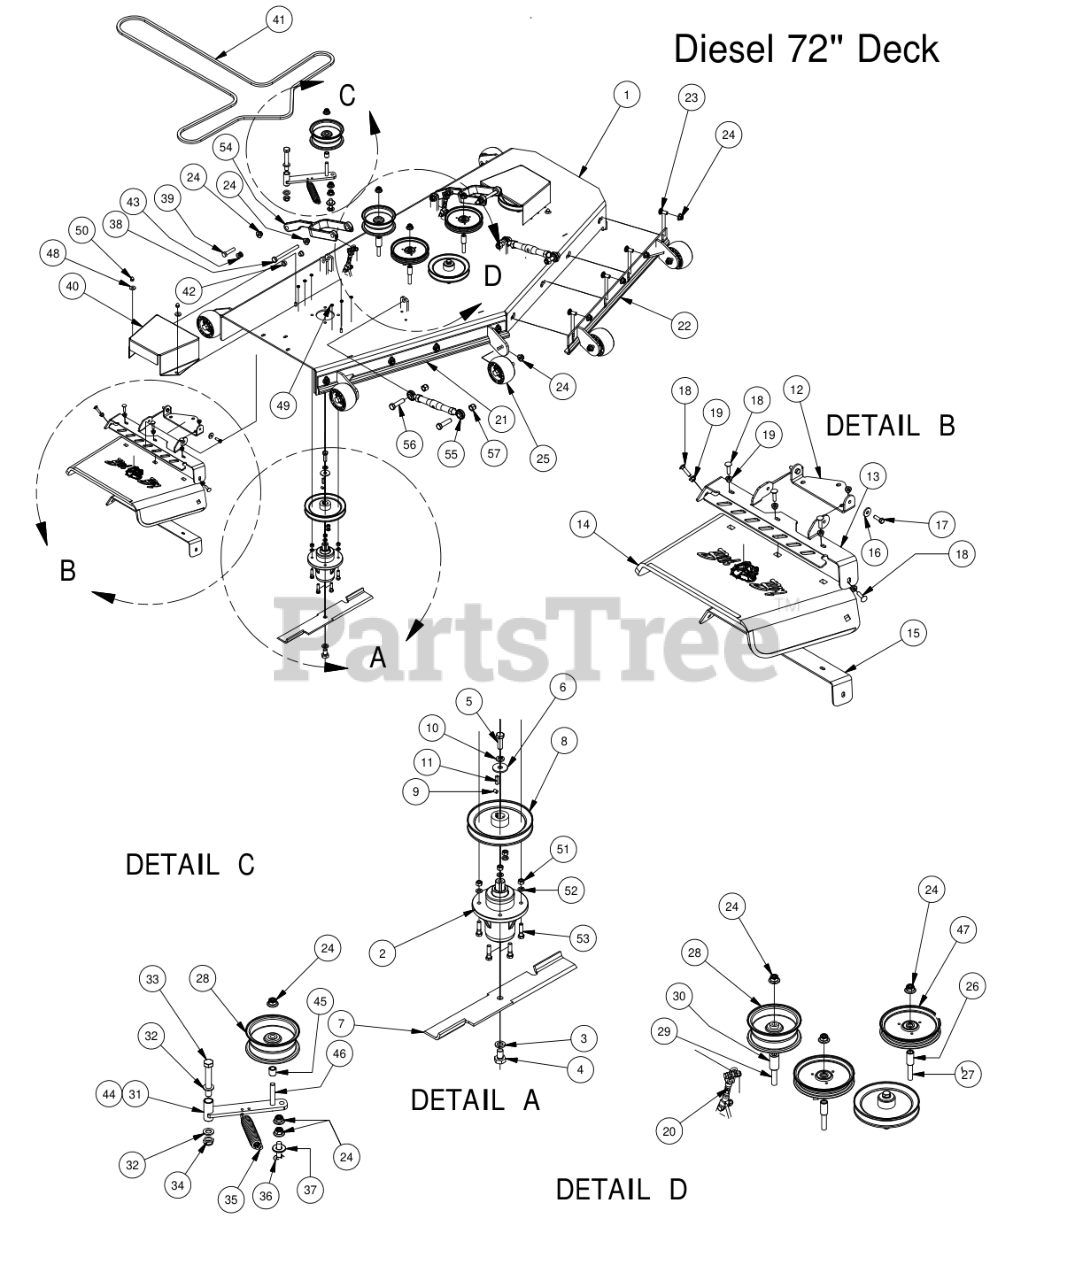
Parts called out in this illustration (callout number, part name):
1	72" (Deck Only)
2	Double Bearing Spindle
3	5/8" Lock Washer
4	5/8" x 1 1/2" Grade 8 Hex Bolt (Fine)
5	1/2"-20 x 1 1/2 - Grade 5 Fine Thread Bolt
6	1/2 Belleville Washer
7	72" High Lift Fusion Blade
8	7" Deck Pulley
9	5/16 Set Screw
10	1/2" Lock Washer
11	1/4" x 1" Key
12	Discharge Chute Hanger (deck mounted)
13	60" Upper Discharge Chute Bracket
14	Rubber Discharge Chute
15	60" Lower Discharge Bracket
16	.360 ID Plastic Washer
17	5/16" x 1" Bolt
18	5/16" x 1 1/4" Carriage Bolt
19	5/16" Nylon Flange Nut
20	5-Link Adjustable Deck Hange
21	72" Deck Adustable Front (Right)
22	72" Deck Adjustable Front (Left)
23	1/2" x 1 1/4 Carriage Bolt
24	1/2-13 Nylon Insert Flange Nut
25	Anti-Scalp Rollers
26	.502 ID X.750 OD X 1.500 Long Spacer
27	1/2 x 3 1/2 Flange Bolt Grade 8
28	5 3/4" Deck Idler Pulley
29	1/2" x 4" Bolt (Grade 8)
30	1 3/4" Pulley Spacer
31	Deck Idler
32	.630 ID Plastic Washer
33	5/8" x 4" Hex Bolt
34	5/8-11 Nylon Insert Jam Half Nut
35	2015 Deck Idler Spring Outlaws
36	1/2 x 2" Carriage Bolt
37	.517 Square Hole Round Washer
38	1/2" x 5 1/2" Bolt
39	1/2-13X 2-1/4 GR Hex Bolts
40	72 Spindle Cover
41	B252-50 Fits 2007 72" Diesel
42	Flange Bushing For Upper Deck Arm
43	Flange Bushing For Lower Deck Arm
44	Deck Idler Complete Assembly- Componets 29,34,37,57,58
45	Spacer 3/4 OD x 1/2 ID x 3\4 Length
46	1/2-13 x GR 5 Hex Bolt Zinc
47	5-3/4 Idler Pulley-Capitol Stampings
48	.360 ID Plastic Washer-Black
49	Black, Round Stick-On Rubber Bumpon
50	Acorn nut-pulley Cover
51	3/8" Hex Nut
52	3/8" Lock Washer
53	3/8" x 1 1/2" Hex Bolt
54	Deck Arm Assembly
55	Turnbuckle (Top Link)
56	5/8" x 2 1/2" Grade 5 Hex Bolt (Coarse)
57	5/8 Std NC Nylock Nut
